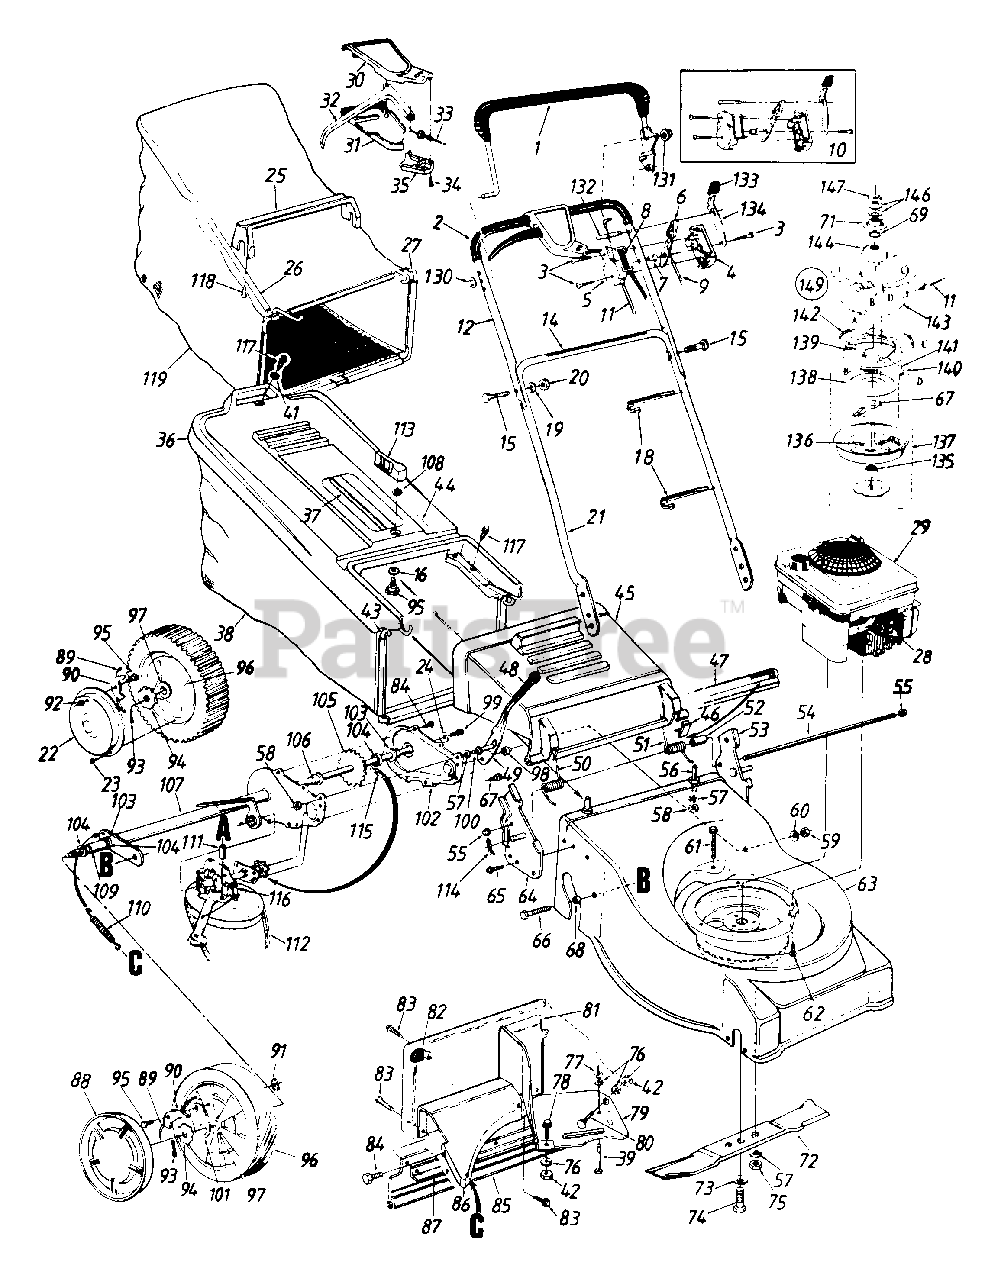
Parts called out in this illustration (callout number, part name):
1	Control Handle Ass'y.
2	Grip
3	Truss Mach. B-Tap Scr. #12 x 1.5" Lg.
4	Control Panel Half
5	Clutch Panel Half
6	Throttle Control Lever
7	Control Disc Pin
8	Control Label - Throttle
9	Throttle Wire - 58" Lg.
10	Control Housing Comp.
11	Control Cable - 52" Lg.
12	Upper Handle
14	Instruction Label - Handle
15	Curved Carriage Bolt 5/16-18 x 1.38" Lg.
16	Bowed Washer
18	Cable Tie
19	L-Wash. 5/16" I.D.
20	Hex Nut 5/16-18 Thd.
21	Lower Handle
22	Hub Cap
23	Pan Hd. Tap Scr. #12 x .50" Lg.
24	Bell-Wash..265" I.D. x .75"
25	Bag Handle
27	Front Catcher Frame
28	Spark Plug Boot
29	Engine
30	Control Cover Half - Upper
31	Control Cover Half - Lower
32	Control Lever
33	Drive Cable - 53" Lg.
34	Flat C-Sunk Hd. Tap Scr. #10 x .75" Lg.
35	Cable Mtg. Cap
36	Hardtop Bag Cover
37	Hardtop Handle
38	Grass Bag
39	Truss Mach. Scr. 1/4-20 x 1.0" Lg.
41	Fl-Wash..281" I.D. x .62"
42	Hex Nut 1/4-20 Thd.
43	Front Catcher Frame
46	Deflector Plug
47	Seal - Extrusion
49	Spring Lever
50	Torsion Spring - R.H.
51	Torsion Spring - L.H.
52	Spacer .255" I.D.
53	Handle Brkt. Ass'y.- L.H.
54	Hinge Pin 17.75" Lg.
55	Cap Speed Nut
56	Shld. Pin 3/8-24 x 1.43" Lg.
57	L-Wash. 3/8" I.D.
58	Hex Jam Nut 3/8-24 Thd.
59	Hex L-Nut 3 8-24 Thd.
60	Bell-Wash..38" I.D. x .88"
61	Hex Wash. Hd. Tap Scr. 1/4-20 x 1.5" Lg.
62	Hex L-Wash. Hd. Scr. 3/8-16 x 1.0" Lg.
63	21" Deck Ass'y.
64	Handle Brkt. Ass'y.- R.H.
65	Hex L-Wash. Hd. AB-Tap Scr. 1/4 x .62" Lg.
66	Hex Wash. Hd. Tap Scr. 3/8-16 x .75" Lg.
67	Hex Wash. Hd. Tap Scr. 1/4-20 x .5" Lg.
68	Spacer .383" I.D.
69	Serrated Washer 1.0" I.D.
71	Serrated Pulley Half
72	21" Blade
73	Bell-Wash..46" I.D. x .88"
74	Hex Bolt 7/16-20 x 2.0" Lg. (Gr. 5)
75	Hex Nut 3/8-24 Thd. (Gr. 8)
76	L-Wash. 1/4" I.D.
77	Hex Jam Nut 1/4-20 Thd.
78	Hex Bolt 1/4-20 x .85" Lg.
79	Rear Belt Baffle
80	Carr. Bolt 1/4-20 x .50" Lg.
83	Torx Mach. AB-Tap Scr. 1/4 x .62" Lg
84	Hex B-Tap Scr. 1/4 x .38" Lg.
85	Rear Flap
89	Plastic Spring
90	Pawl .345" I.D.
91	Weld Nut 1/4-20 Thd.
92	Hex Ins. L-Nut 1/4-20 Thd.
93	Cotter Pin 1/8" Dia.
94	Ratchet Wheel 1.62" O.D.
95	Shld. Bolt .342" Dia. x .268"
96	Wheel Ass'y. Comp.- Rear
97	Flange Ball Bearing 1/4" I.D.
98	Shld. Spacer .50" Dia.
99	Hex Bolt 1/4-20 x .62" Lg. (Gr. 5)
100	Shld. Pin 3/8-24 x 1.43" Lg.
101	Pawl Plate
104	Fl-Wash..531" I.D. x .93"
105	Rear Axle Ass'y.
106	Hex Flange Bearing
109	Spacer.513" I.D.
110	Extension Spring 3.8" Lg.
111	Spacer.325" I.D.
112	V-Belt
113	Grass Catcher Locking Knob
114	Internal Cotter Pin 5/16" Dia.
115	#48 Chain .50" Pitch x 30 Links
116	Transmission Comp.(See Breakdown)
117	Hex L-Wash. Hd. AB-Tap Scr.'/4 x .62" Lg. f f
118	Hex AS-Tap Scr. #12 x 1.25" Lg t
119	Grass Bag f
130	Push Cap
131	Push Cap
132	Lock Pin .314" Dia. x 1.75"
133	Spring Lever Knob
134	Lockout Spring
135	Ball Brg..669" I D x 1 574"
136	Comp. Spring .35" O.D. x 2.0" Lg.
137	Clutch Blade Housing Ass'y.
138	Clutch Cone
139	Brake Cup Cone
140	Ball Block
141	Steel Ball .50" Dia.
142	Ext. Spring 1.75" Lg.
143	Clutch Housing
144	Fixed Pulley Adapter
146	Bell-Wash. 1.01" I.D.
147	Crankshaft Spacer
149	Blade Brake Clutch Ass'y. Comp.
